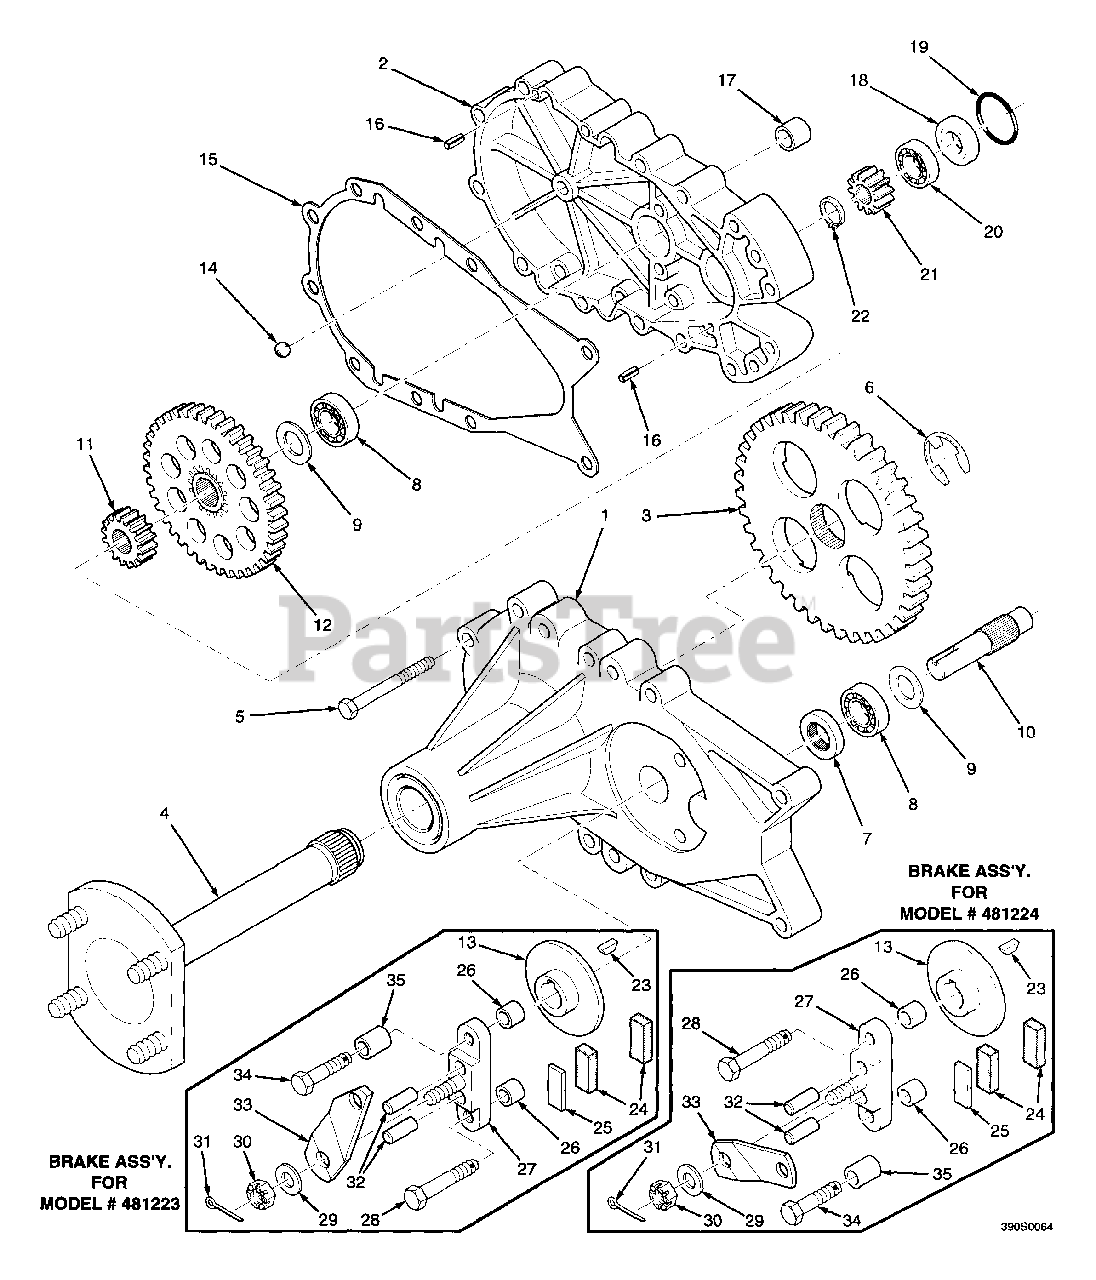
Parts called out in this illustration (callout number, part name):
1	Axle Housing Assembly
2	Hydro Mount Housing
3	Splined Final Gear Drive
4	Axle Shaft Assembly
5	Bolt, 1/4-20 x 2-1/2 Hex Head
6	E-Ring
7	Oil Seal, 1.25 x .625"
8	Ball Bearing, .62 ID x 1.38 x .44"
9	Washer, HT. 62 ID x 1.0 OD x .05 Thick
10	Brake Shaft (Splined)
11	Splined Reduction Gear, 17 Tooth
12	Splined 60 Tooth Gear
13	Disc, Brake
14	Ball, 3/8 Diameter
15	Gasket, Housing
16	Pin, Spring, 3/16 x 1/2 x 1/2 Long
17	Mounting Spacer
18	Bearing, Spacer
19	O-Ring
20	Ball Bearing, 15mm x 35mm x 11mm
21	Input Gear, 11 Tooth
22	Retaining Ring
23	Key, HI Pro 3/16 x 5/8"
24	Puck, Brake
25	Plate, Puck
26	Brake Spacer
27	Brake Yoke Assembly
28	Bolt, 1/4-20 x 1-1/2 Hex Head
29	Washer, 7/16 x 7/8 OD x .06 HT
30	Nut, Castle, 5/16-24 PL
31	Pin, Cotter
32	Pin, Brake Actuating
33	Arm, Brake Actuator (L.H. Assembly)
33	Arm, Brake Actuator (R.H. Assembly)
34	Bolt, 1/4-20 x 2-1/2 Hex Head
35	Spacer
